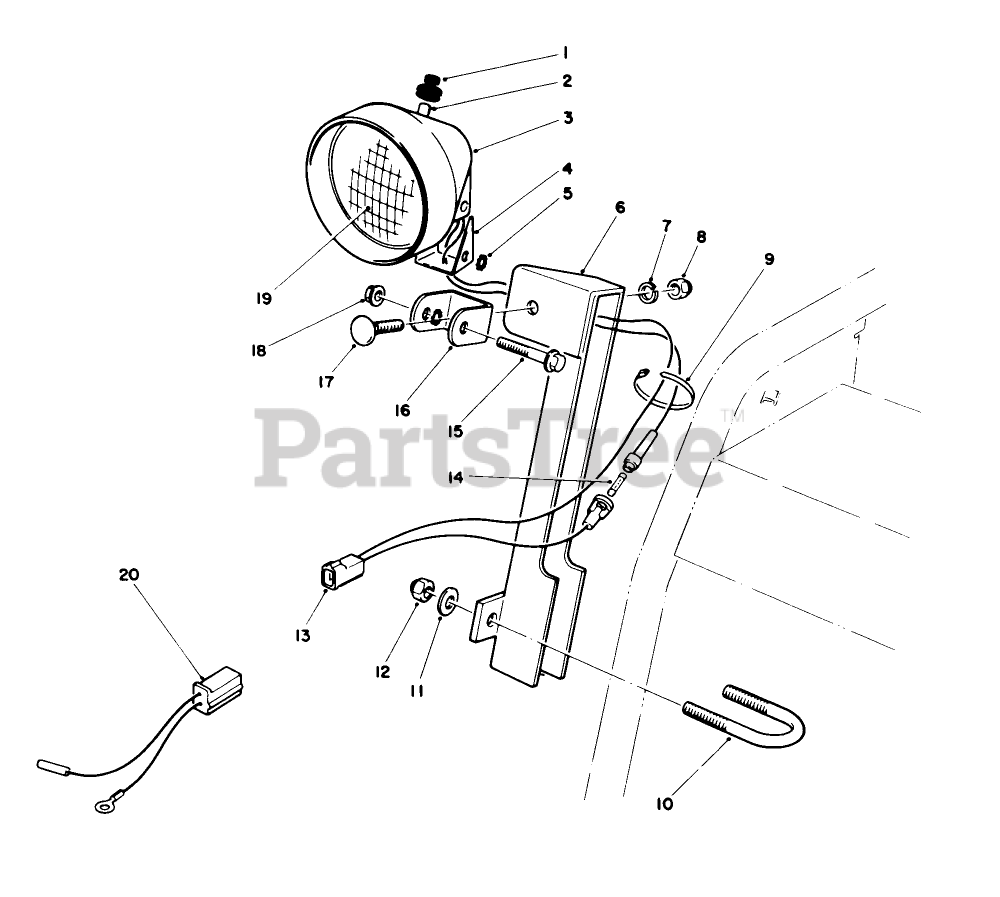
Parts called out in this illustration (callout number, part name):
1	BOOT-SWITCH
5	WASHER-LOCK
7	WASHER-LOCK
8	NUT-HEX
9	TIE-CABLE
10	U-BOLT
11	WASHER-PLAIN
12	NUT-LOCK, NI
13	WIRE ASM
14	Fuse-7-1/2 Amp.
15	SCREW-HH
17	BOLT-CARR
18	NUT-HF
20	WIRE ASM
